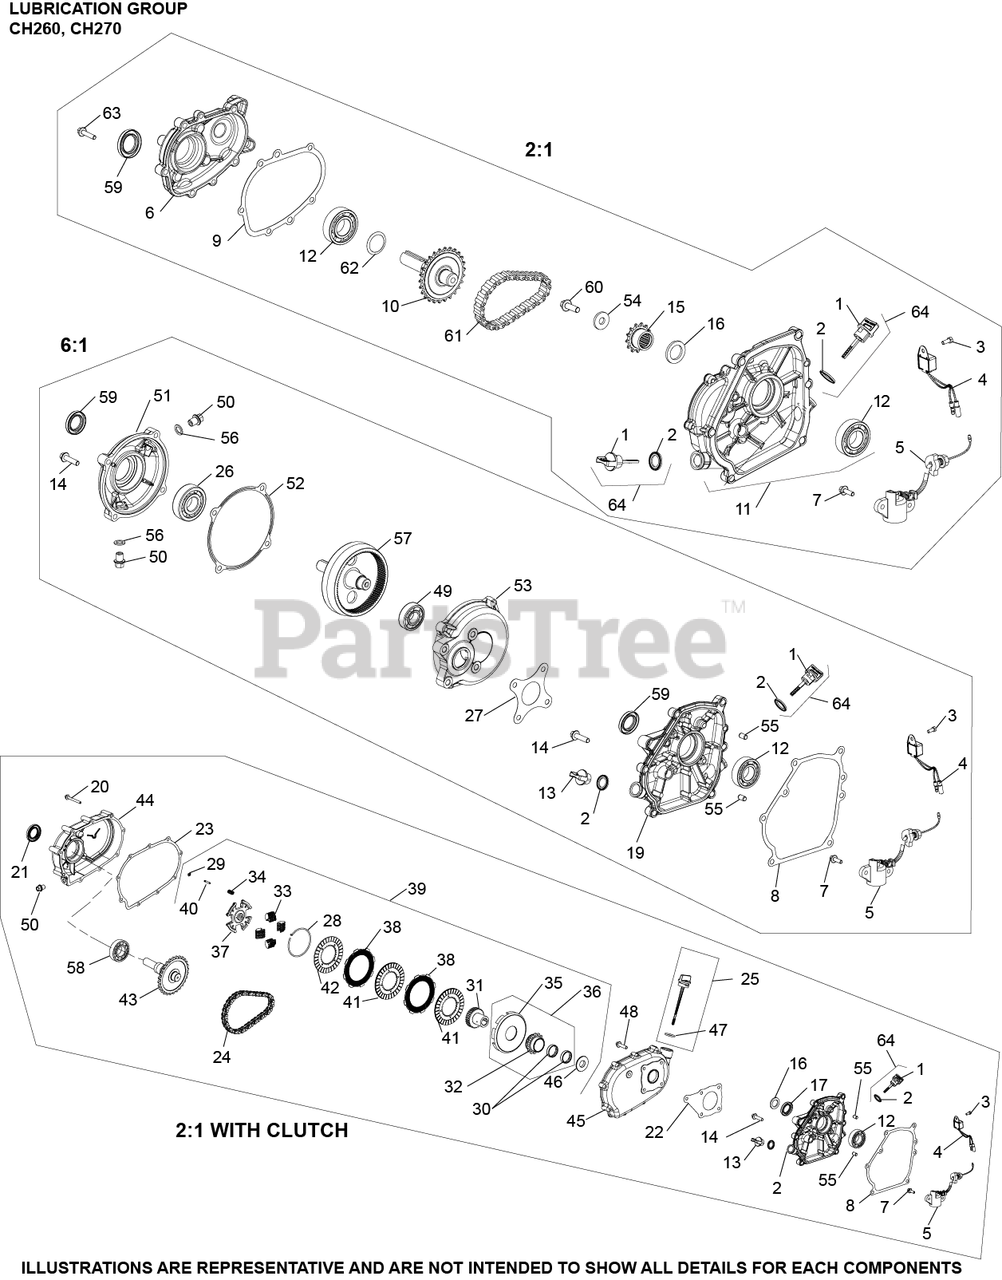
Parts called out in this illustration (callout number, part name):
1	DIPSTICK - USE 17 038 08-S
2	SEAL, OIL
3	SCREW, HEX/PHILLIPS M5
4	CONTROL, OIL ALERT UNIT
5	SWITCH, OIL SENSOR ASSEMBLY
6	COVER, CHAIN
8	GASKET, CLOSURE PLATE
9	GASKET, CHAIN COVER
10	SHAFT, PTO SPROCKET
11	PLATE , CLOSURE
14	SCREW, CLOSURE PLATE
15	GEAR, PINION
16	SPACER, PINION
54	WASHER, FLAT
59	SEAL, CLOSURE PLATE
60	SCREW, HEX FLANGE (M8) (CKY)
62	WASHER, SPRING
63	SCREW, HEX FLANGE (M6)
64	DIPSTICK ASSEMBLY
